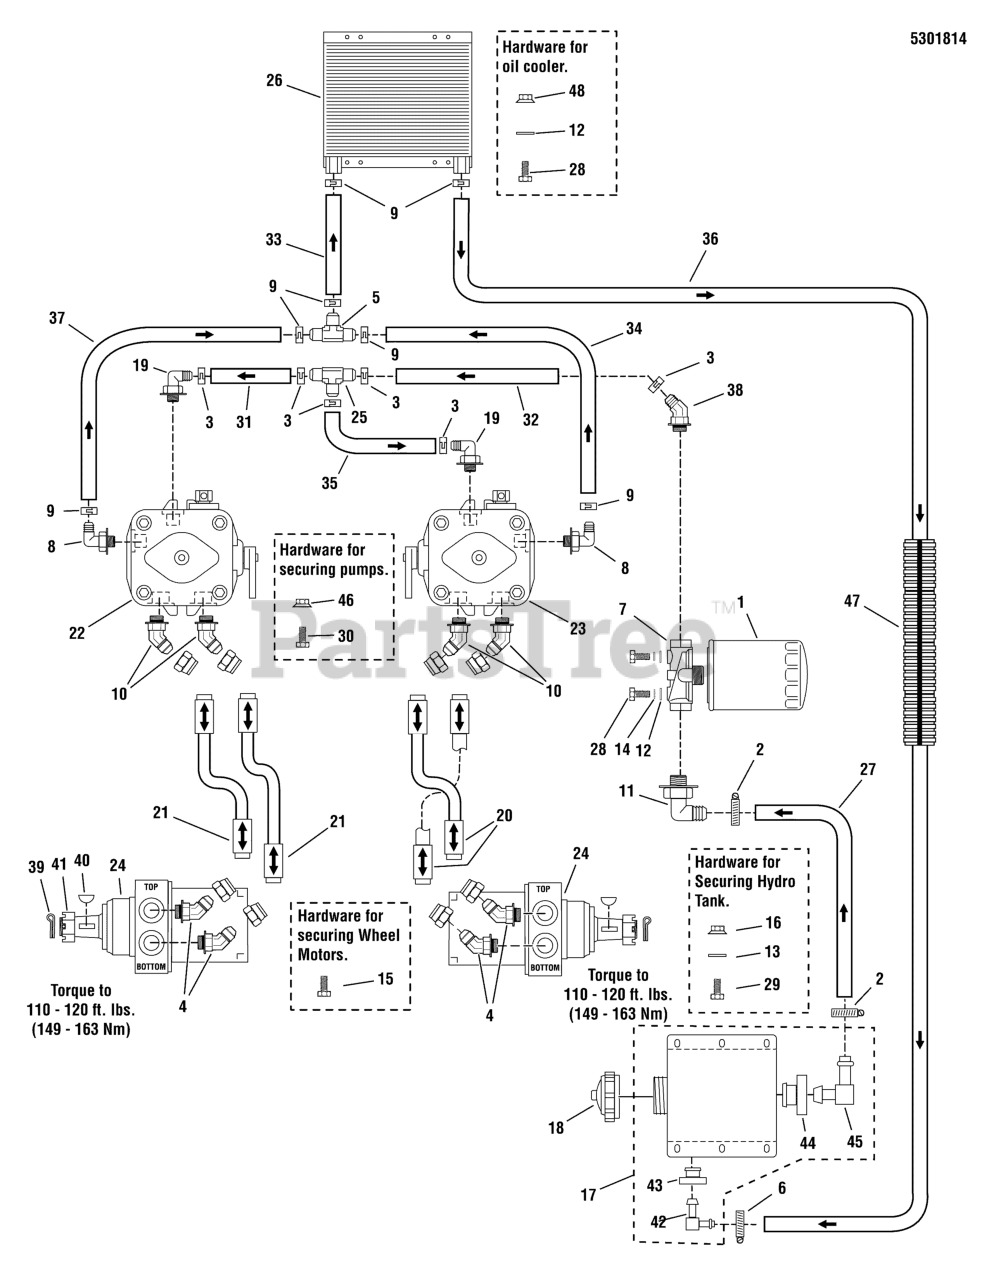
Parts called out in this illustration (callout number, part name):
1	FILTER, OIL
2	CLAMP, #10 HOSE, STAINLESS
3	CLAMP, HOSE, EXTERNAL, 3/4
4	FITTING, #8 JIC - #10 O-RING, 45 DEG.
5	FITTING, TEE, 1/2 HOSE
6	CLAMP, #4 HOSE, STAINLESS
7	FILTER HEAD, HYDRAULIC
8	ADAPTER, 90 DEG, 9/16-3/8 BARB
9	CLAMP, HOSE
10	FITTING, #8 JIC - #8 O-RING, 45 DEG.
11	ADAPTER, 90 DEG, 9/16-5/8 BARB
12	WASHER, 1/4 SAE
13	WASHER, 5/16" SAE
14	WASHER, 1/4 LOCK
15	BOLT,HEX FLG, SER GD8 3/8-16X1, PATCH
16	NUT, 5/16-18 HEX NYLOCK FLANGE
17	TANK, HYDRAULIC, ASSEMBLY
18	CAP, HYDRAULIC, SHIELDED VENT
19	FITTING, 9/16 O-RING-1/2" HOSE, 90 DEG
20	HOSE ASM,RH, LH PUMP PORT BOT MOTOR PORT
21	HOSE ASM,LH, LH PUMP PORT BOT MOTOR PORT
22	PUMP, 12CC-LH,HGEAR (PK-2HBQ-LV1X-XXXX)
23	PUMP, 12CC-RH, HGEAR(PK-2KBQ-L81X-XXXX)
24	WHEEL MOTOR, HGM-15P-7131
25	FITTING, BEADED TEE, 1/2 X 1/2 X 1/2, YZ
26	OIL COOLER, .75 X 11.0 X 24 PLATES
27	HOSE, OIL SUPPLY, RES-FILTER
28	BOLT, 1/4-20 X 3/4 GD5 YZ
29	BOLT, 5/16-18 X 1 GD5 YZ
30	BOLT, 7/16-14 X 1-1/4 GD5 YZ
31	HOSE, 1/2" PUSH-ON, 17.50"
32	HOSE, 1/2" PUSH-ON, 8.50"
33	HOSE, 3/8" PUSH-LOCK, 12.00"
34	HOSE, 3/8" PUSH-LOCK, 17.25
35	HOSE, 1/2" PUSH-ON, 3.50"
36	HOSE, 3/8" PUSH-LOCK, 42.00"
37	HOSE, 3/8" PUSH-LOCK, 8.50"
38	FITTING, 45 ELBOW, 1/2" HOSE TO 9/16 O R
39	PIN, COTTER, 1/8 X 2" (SV)
40	WOODRUFF KEY (SV)
41	NUT, CASTLE, 3/4-20
42	FITTING, ELBOW, 3/8" (SV)
43	BUSHING-FUEL TANK RED RUBBER
44	GROMMET (SV)
45	FITTING, ELBOW, 5/8" (SV)
46	NUT, HEX, 7/16-14, SER, FLG, GD5, YZ
47	WIRE LOOM, 5/8 ID 36" LONG
48	NUT, 1/4-20 HEX NYLOCK FLANGE
